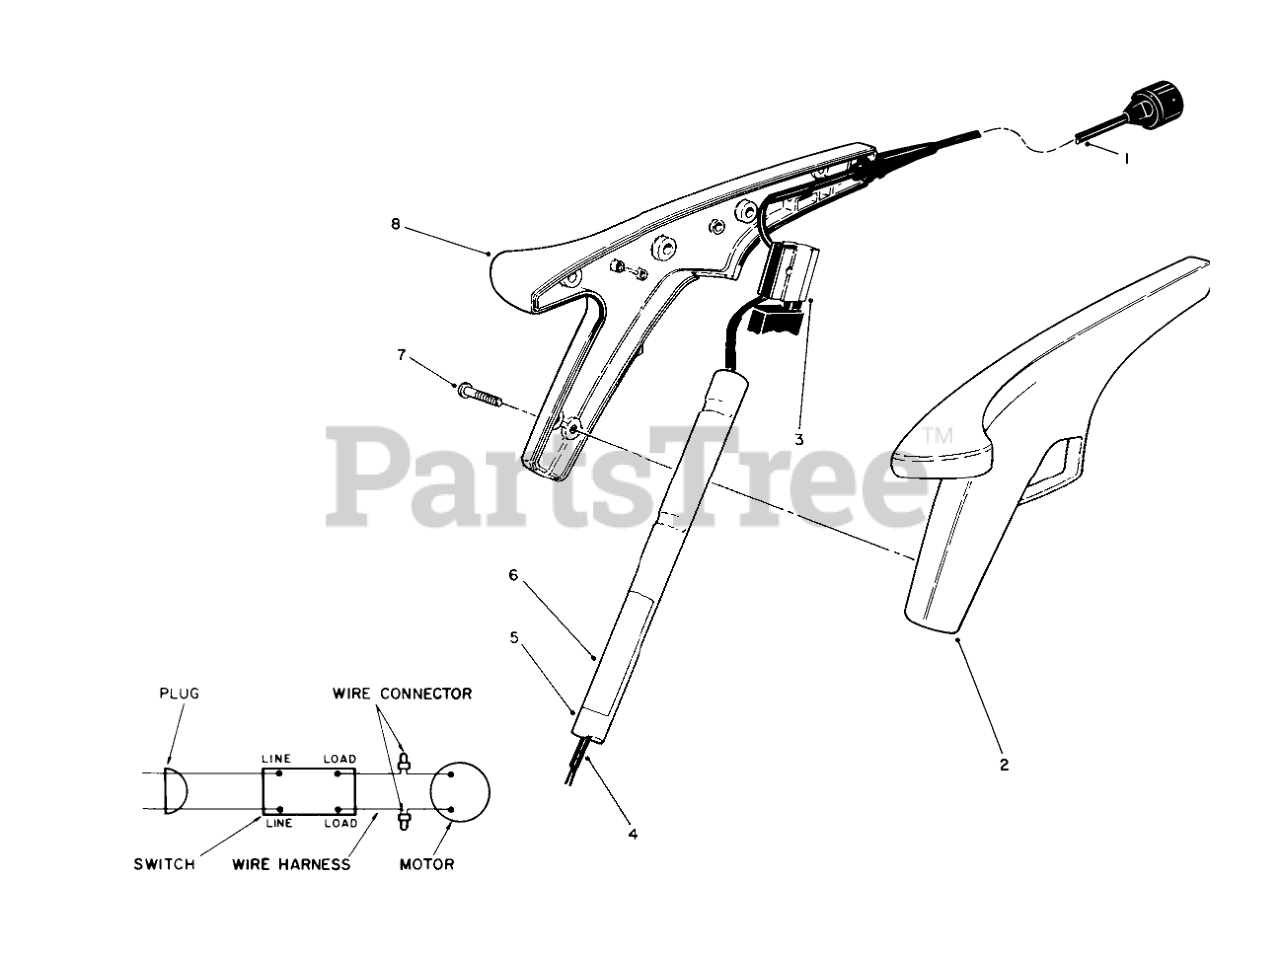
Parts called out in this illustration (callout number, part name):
1	CORD-SUPPLY
2	HAND GRIP, 8" - L.H.
3	SWITCH SINGLE SPEED
4	WIRE HARNESS
5	TUBE EXTENSION
6	REP. SERIAL PLT
7	#8 X .625" PHILPS PAN H
8	HAND GRIP, 8" - R.H.
